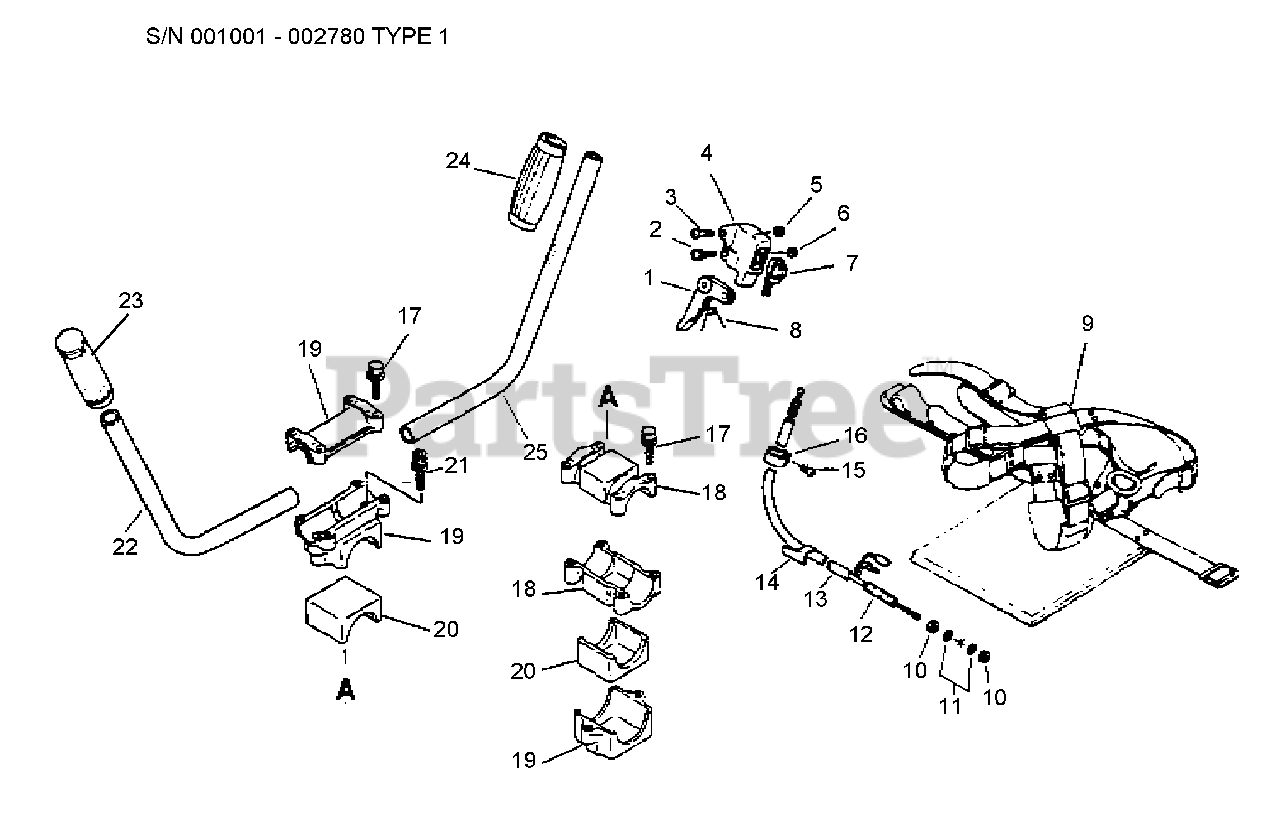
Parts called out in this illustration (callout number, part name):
1	TRIGGER, THROTTLE
2	SCREW - 5X30
3	SCREW - 5X30
4	BRACKET, THROTTLE
5	LOCKNUT - 5
7	IGNITION SWITCH ASSY
8	SPRING, TRIGGER
9	SHOULDER STRAP ASSY
10	LOCKNUT - 6
11	WASHER - 6
12	CABLE, THROTTLE
13	TUBE - VINYL
15	SCREW - 5X10
17	BOLT - 5X25
18	BRACKET KIT
19	BRACKET ASSY
20	CUSHION
21	SCREW - 5X25
22	HANDLE, FRONT - LEFT
23	GRIP, HANDLE - LEFT
24	GRIP, HANDLE
